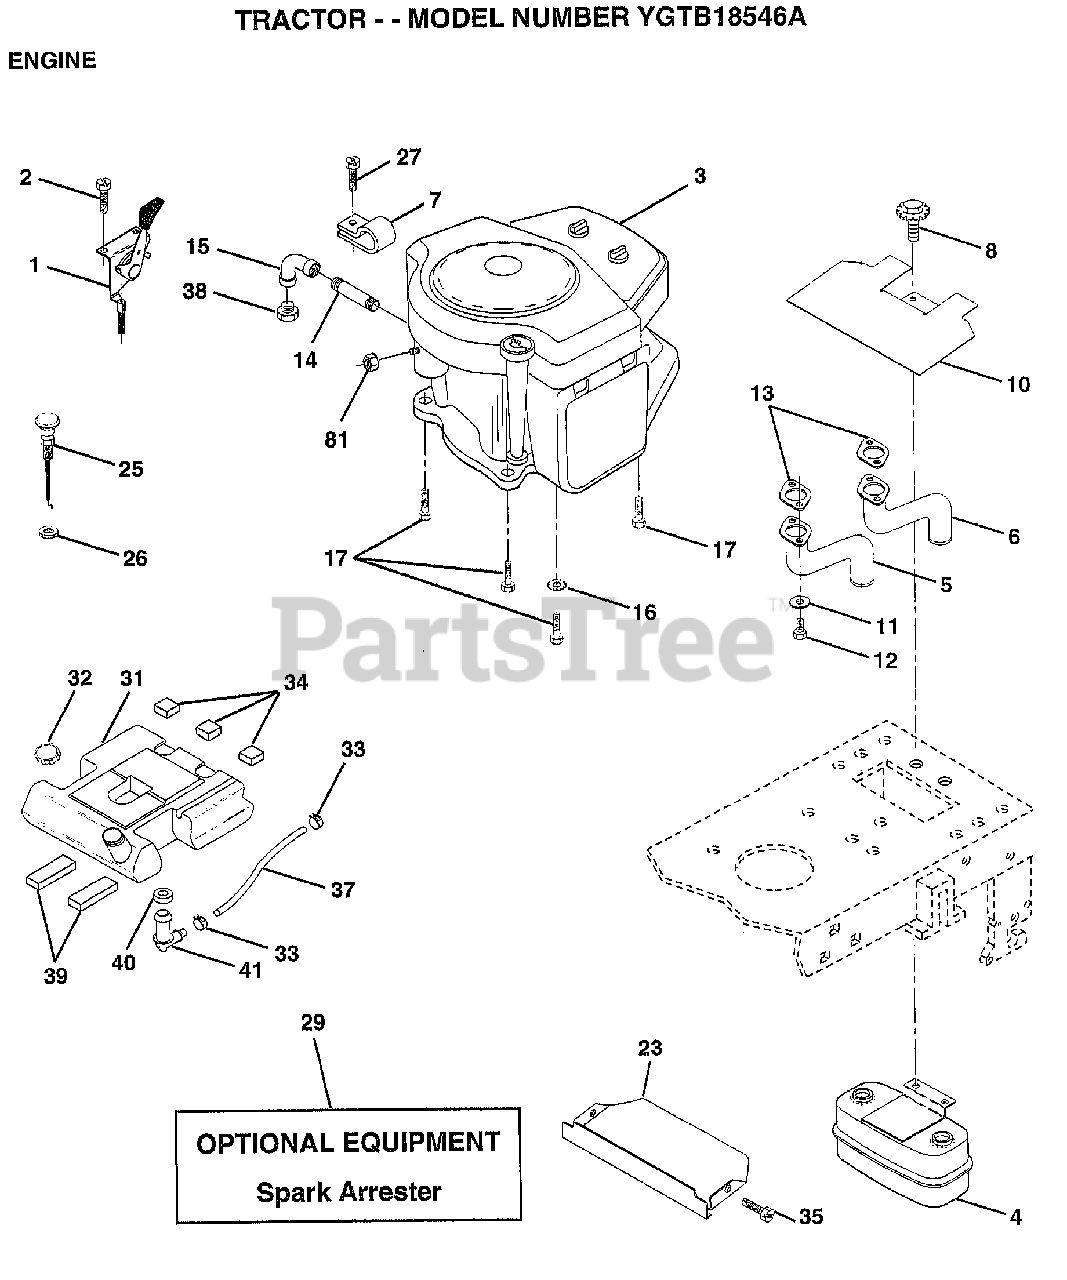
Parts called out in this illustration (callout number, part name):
1	CONTROL THRT 35.5
2	SCREW LT
4	MUFFLER.TW.LOTONE
5	EXHAUST.B&S.18.RH
6	EXHAUST.B&S.18.LH
7	CLAMP.TUBE.DBL.EN
8	BOLT.5/16-18.UNC
10	SHIELD.HEAT.
11	LOCKWASHER
13	GASKET MUFFLER
14	PIPE NIPPLE LT
15	ELBOW
16	LOCKWASHER
17	SCREW LT
23	SHIELD.BRN/DBR.GD
25	CONTROL.CHOKE.37
26	"NUT,KEPS 3/8-24IM"
27	"SCREW-TT,10-32 FL"
31	TANK FUEL REAR
32	CAP ASM FUEL
33	HOSE CLAMP
34	PAD-SPACER LT
35	SCREW
37	FUEL LINE T
39	PAD IDLER TI
40	BUSHING OUTLET T
41	STEM.TANK.FUEL
81	NUT
